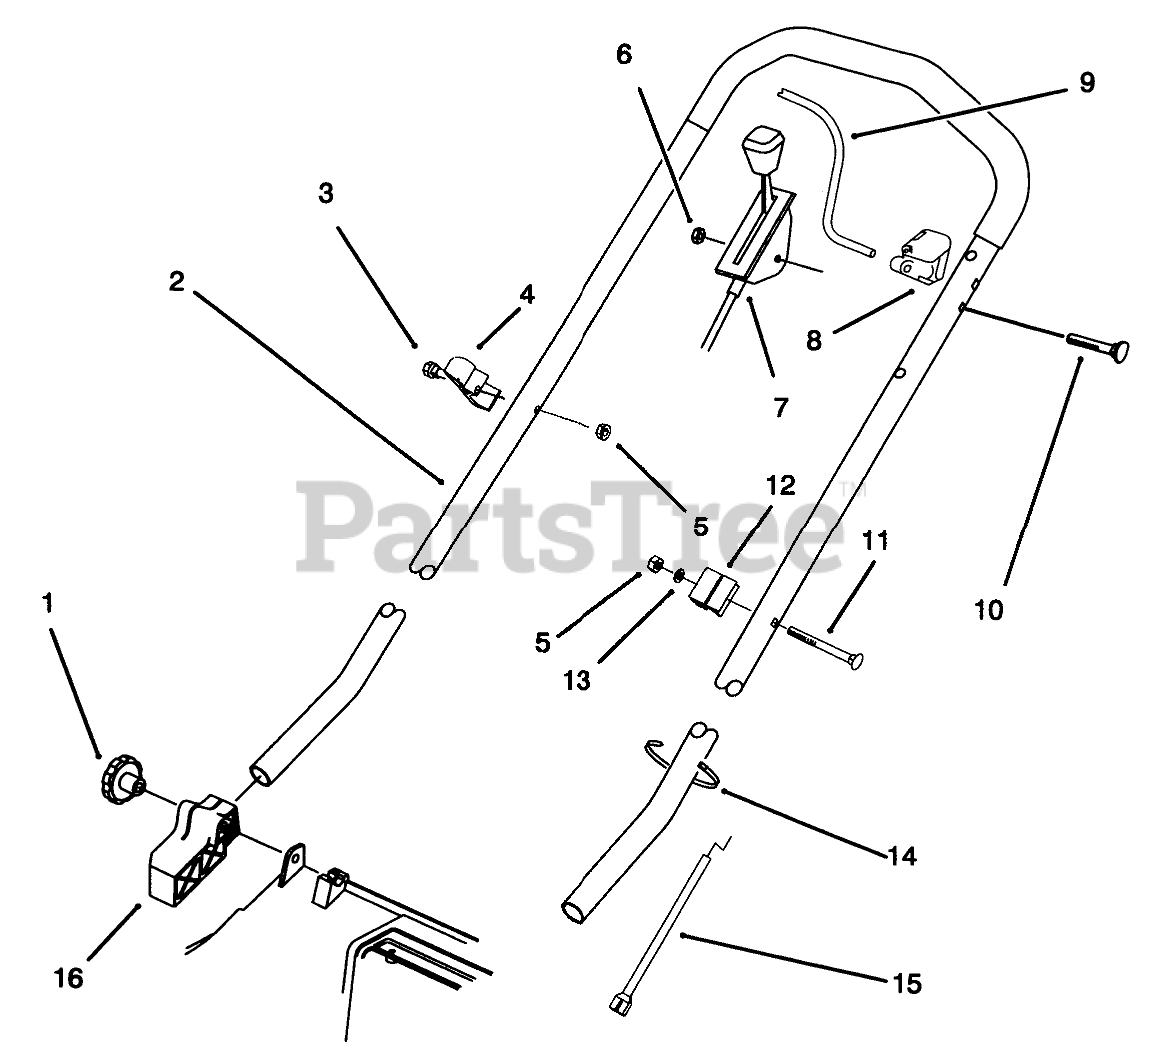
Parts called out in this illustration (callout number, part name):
2	HANDLE (DIPPED)
3	.250-20X1.625 HH SCREW
4	GUIDE - ROPE
5	NUT-LOCK, NI
6	NUT-LOCK, NI
7	CONTROL - THROTTLE
8	STOP-PIVOT
9	BAIL - CONTROL
10	SCREW-HANDLE
11	SCREW-HANDLE
12	SUPPORT-CABLE
13	WASHER-FLAT
14	TIE-CABLE
15	CABLE - BRAKE
16	MOUNT-HANDLE, RH
